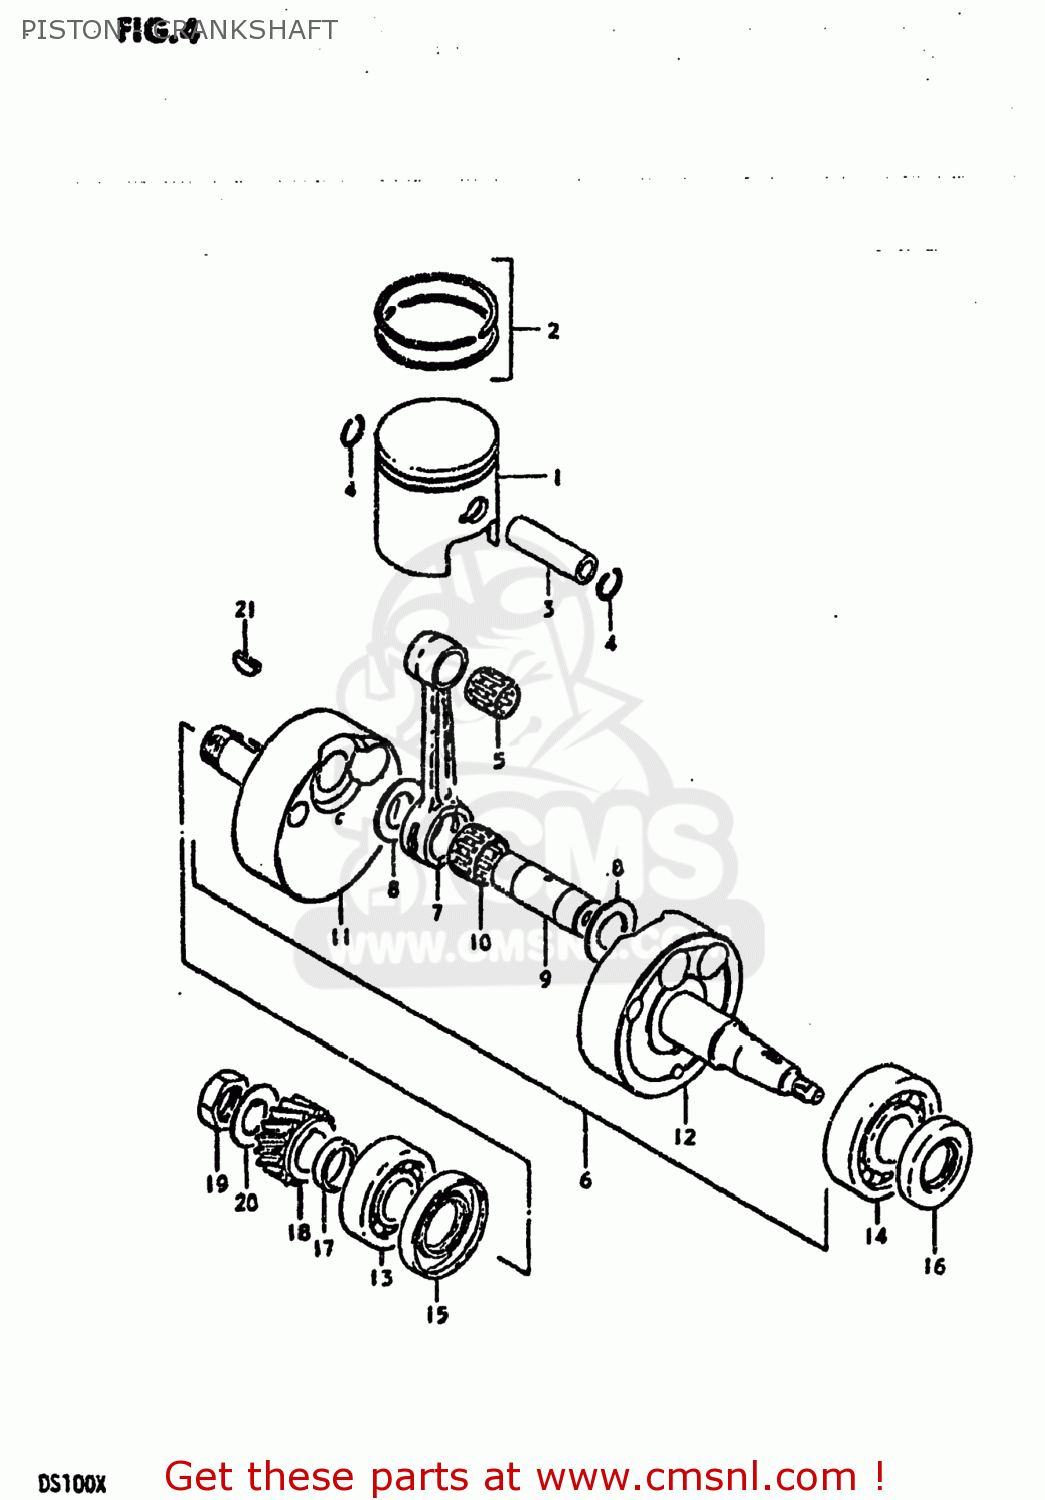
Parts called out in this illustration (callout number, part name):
1	PISTON
2	RING SET,PISTON
3	PIN,PISTON 14MM
4	RING,SNAP 14MM
5	BEARING
6	CRANKSHAFT ASSEMBLY
7	CONNECTING ROD
8	WASHER(19X32X1)
9	PIN,CRANK
10	BEARING
11	CRANKSHAFT,R
12	CRANKSHAFT,LEFT
13	BEARING
14	BEARING(25X62X17)
15	SEAL,OIL(26X52X8)
16	OIL SEAL
17	SPACER(20X28X7)
18	GEAR,PRIMARY DRIVE
19	NUT
20	WASHER
21	KEY
